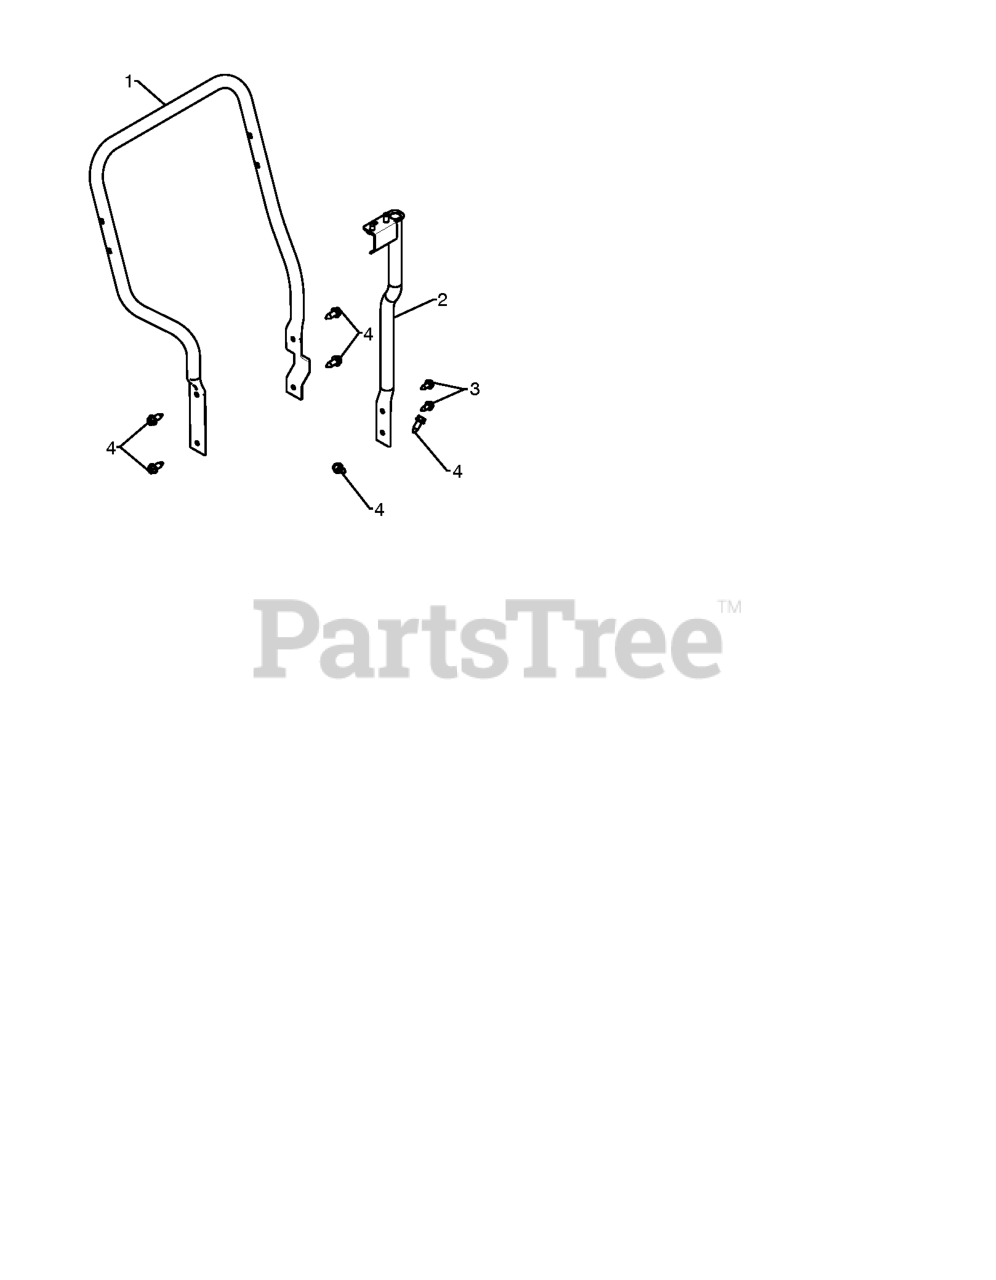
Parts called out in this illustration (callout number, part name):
1	TUBE.LOWER.HANDLE.SNOW.GRAY
2	SUPPORT.WELDMENT.ROTATOR.
3	BOLT.HEX.HD.WASHER.5/16-18X.75
4	SCREW 3/8-16X1
